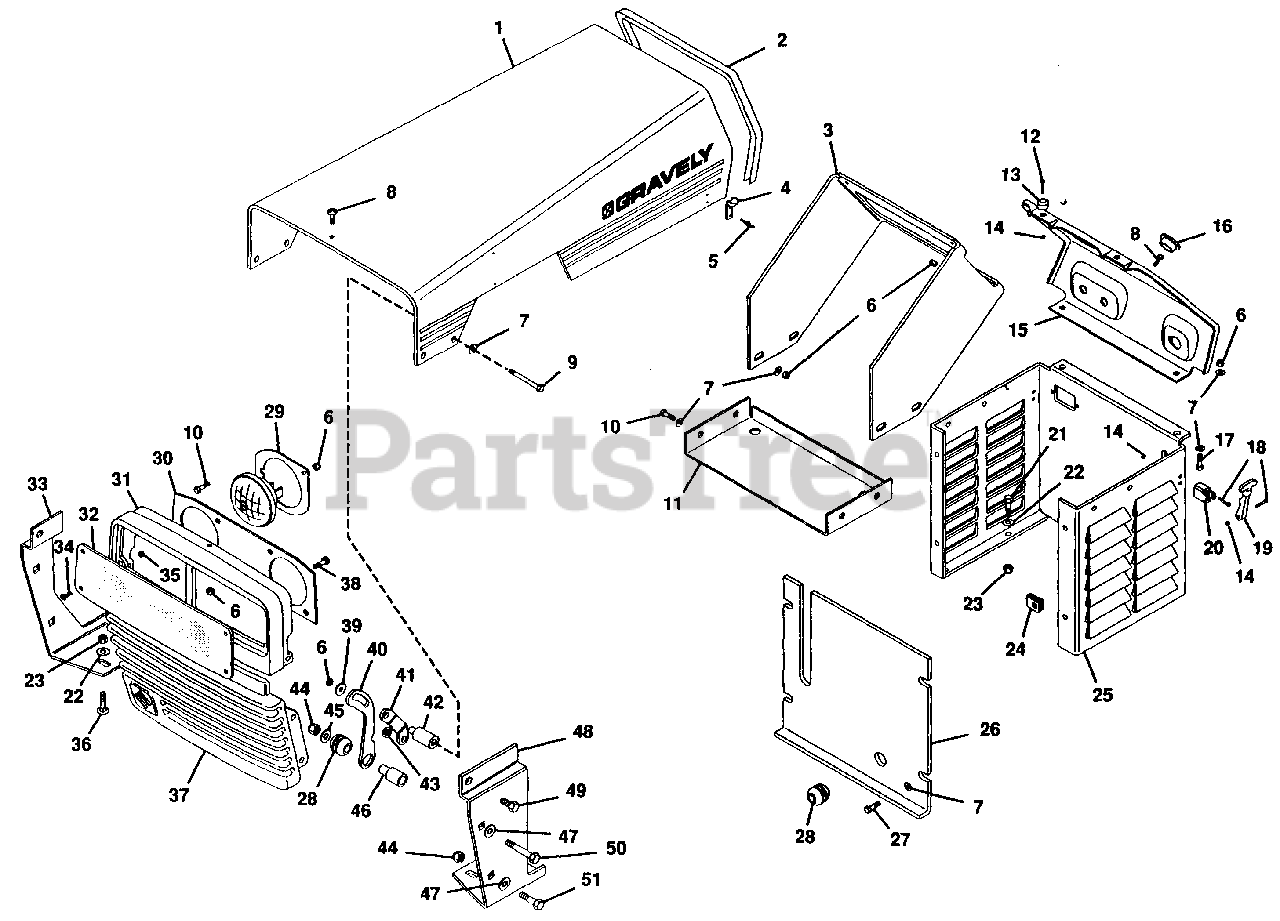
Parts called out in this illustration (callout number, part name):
1	Hood, GEM Silkscreen
2	Strip, Cowl
3	Bracket, Support
4	Keeper
5	Rivet, Dome Head
6	Nut, Lock 1/4-20
7	Washer, Flat .281 x .625 x .065
8	Screw, Mach. 1/4-20 PHD
9	Bolt, Hex 1/4-20 x 2.25
10	Bolt, Hex 1/4-20 x 1.00
11	Tray, Battery
12	Screw, Mach. 6-32 x .625 PHD
13	Bumper
14	Nut, Mach. Lock 6-32
15	Panel, Silkscreen
16	Bush., Flg. .764 x 1.47 x .560 Ny.
17	Bolt, Hex 1/4-20 x .625
18	Screw, Mach. 6-32 x 1.0 PHCR
19	Latch, Flexible Draw
20	Block, Tie-Down
21	Bolt, Hex 5/16-18 x 1.00
22	Washer, Flat .344 x .688 x .065
23	Nut, Lock 5/16-18
24	Nut, Retainer
25	Panel, Silkscreen
26	Cover, Hydraulic Tank
27	Bolt, Hex 1/4-20 x .75
28	Grommet
29	Ring, Headlight Retainer
30	Panel, Headlight Reflector
31	Headlight, Bezel
32	Panel, Headlight Lense
33	Bracket(R.H.)
34	Screw, Mach. 10-24 x .75 PHD
35	Nut, Lock 10-24
36	Bolt, Carriage 5/16-18 x 1.0
37	Casting, Grille
38	Screw, 1/4-20 x .50 Self Tapping
39	Washer, Flat .281 x 1 x .063
40	Hinge, Slotted
41	Hinge, Short L.H.
41	Hinge, Short R.H.
42	Pivot, Hood
43	Nut, Lock 3/8-16
44	Nut, Lock 3/8-16
45	Washer, Flat .438 x 1.000 x .083
46	Bush., .390 x .750 x 1.47 Stl.
47	Washer, Flat .406 x .812 x .065
48	Bracket(L.H.)
49	Bolt, Hex 3/8-16 x .75
50	Bolt, Hex 3/8-16 x 2.75
51	Bolt, Hex 3/8-16 x 1.25
NS	Decal, 12.5
NS	Decal, 14
